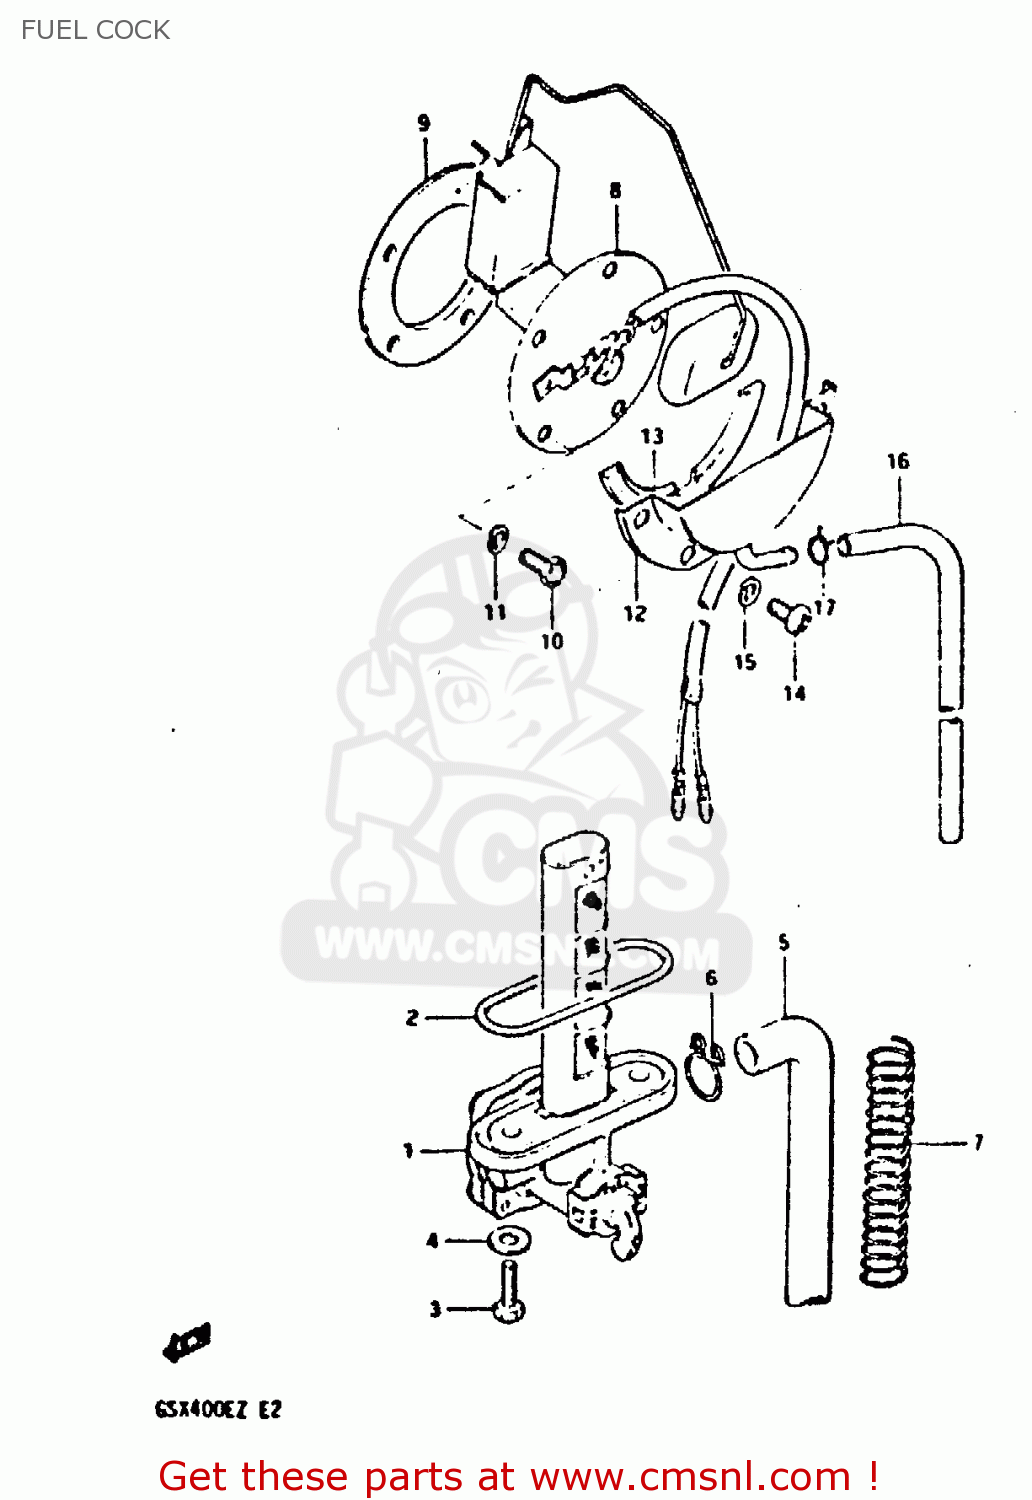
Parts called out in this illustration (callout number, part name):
1	COCK ASSEMBLY,FUEL
2	O RING
3	SCREW
4	GASKET
5	HOSE
6	CLIP
7	SPRING
8	GAUGE ASSEMBLY,FUEL LEVEL
9	GASKET,FUEL LEVEL GAUGE (NAS)
10	BOLT
11	LOCK WASHER
12	PLATE,FUEL DRAIN
13	GASKET (NAS)
14	SCREW
15	LOCK WASHER
16	HOSE,FUEL
17	CLIP
